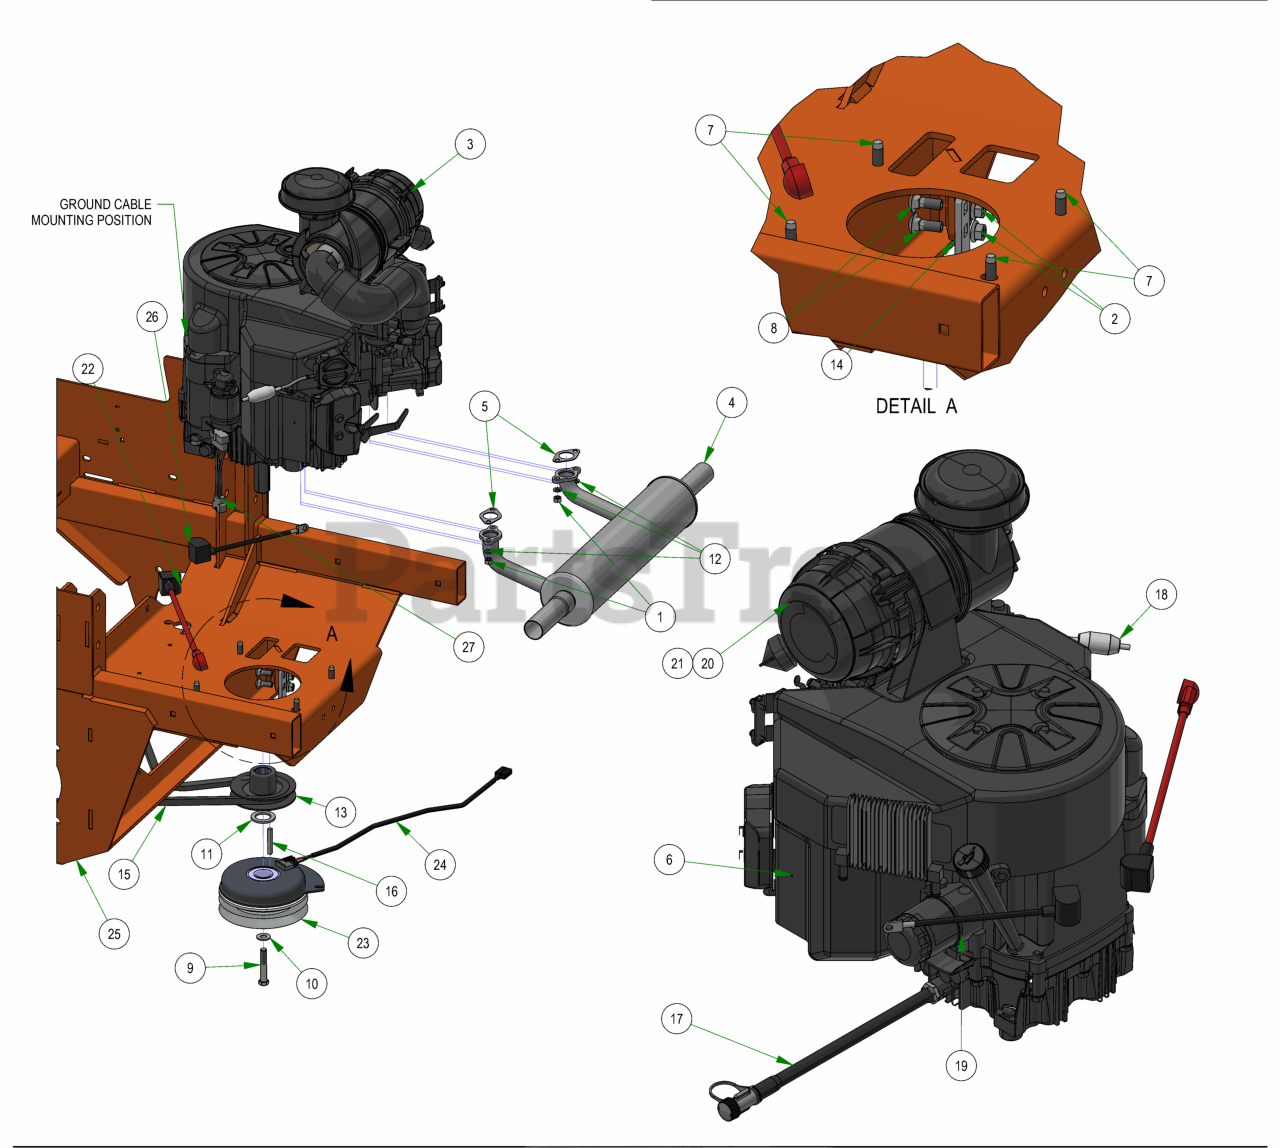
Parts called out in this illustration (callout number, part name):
1	M8-1.25 DIN 934 HEX NUT (CL.8) ZINC
2	3/8-16 NYLON INSERT FLANGE LOCKNUT (GR.F) ZINC
3	Kawasaki Engine FX-850-V-CS09R
4	2019 Rebel/Rogue Kawasaki 850 Muffler
5	Exhaust Gasket
6	Spark Plug - Kawasaki
7	3/8-16 X 1-1/8 HEX WASHER UNSLOT SERRATED (TRI-LOB) TRS ZINC YELLOW
8	3/8-16 X 1 CARRIAGE BOLT (GR.5) ZINC
9	7/16-20 X 2-1/2 HEX Bolt GR 8 W/ Patch
10	3/8 FLAT WASHER USS (1" OD) ZINC
11	1.140 ID X 1.750 OD X .132 THICK FLAT WASHER PLAIN
12	5/16 SPLIT LOCKWASHER ZINC
13	4 3/4 Motor Pulley
14	Rebel Clutch Tab
15	2019 Rebel Pump Belt
16	1/4 X 2 SQ MACHINERY KEY 1018 STL PLAIN
17	Kawasaki Oil Drain
18	Universal Inline Fuel Filter
19	Oil Filter
20	Canister Air Filter- Outer
21	Canister Air Filter- Inner
22	14" Red Battery Cable
24	Clutch Pigtail
25	2023 Rebel Frame - Painted
26	Starter Cable
27	2019 Harness Adaptor-Gen2 FX-ALL
